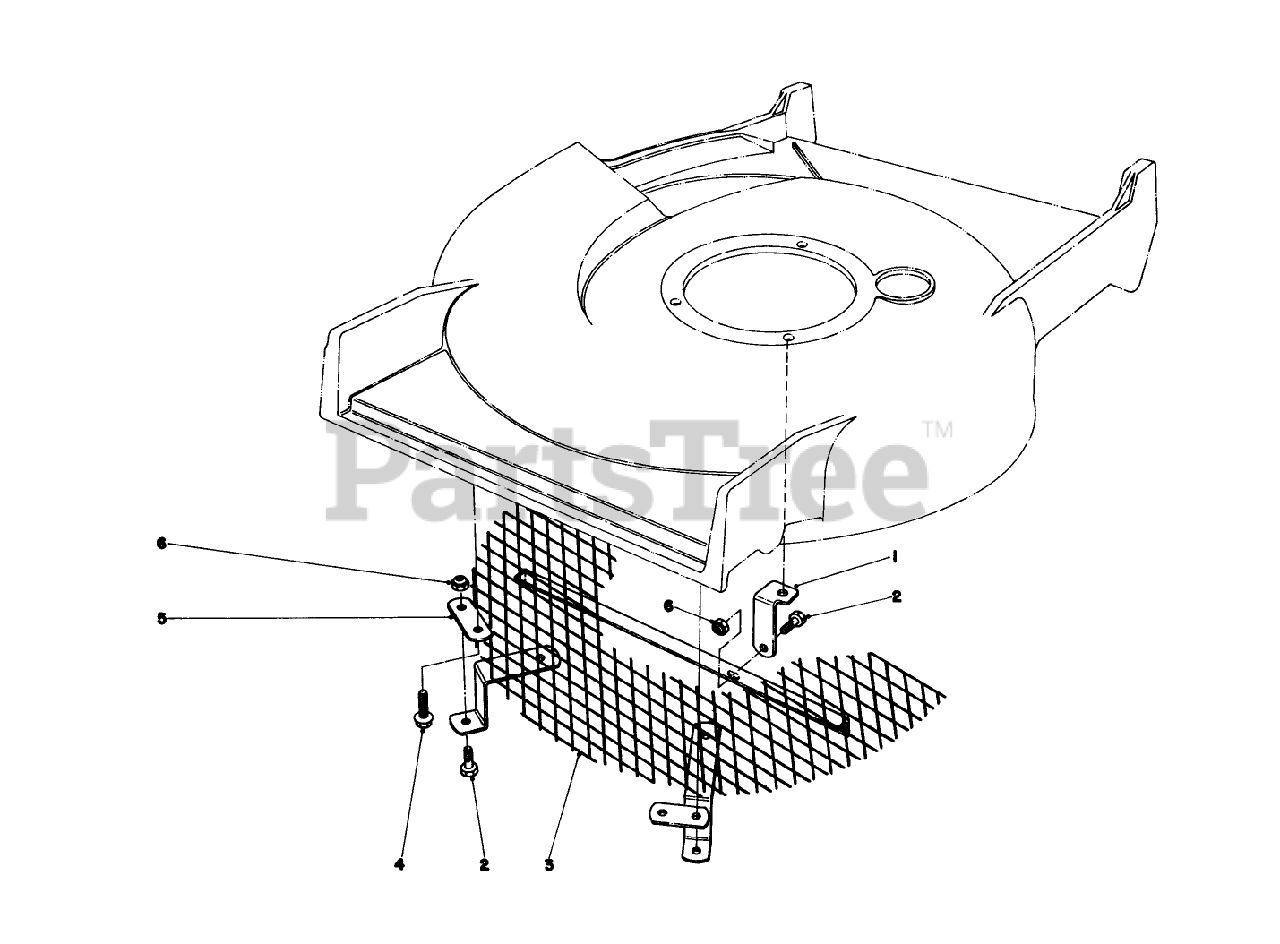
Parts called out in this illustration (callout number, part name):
2	SCREW-HH
4	SCREW-THD ROLL, HWH
6	NUT-LOCK, NI
